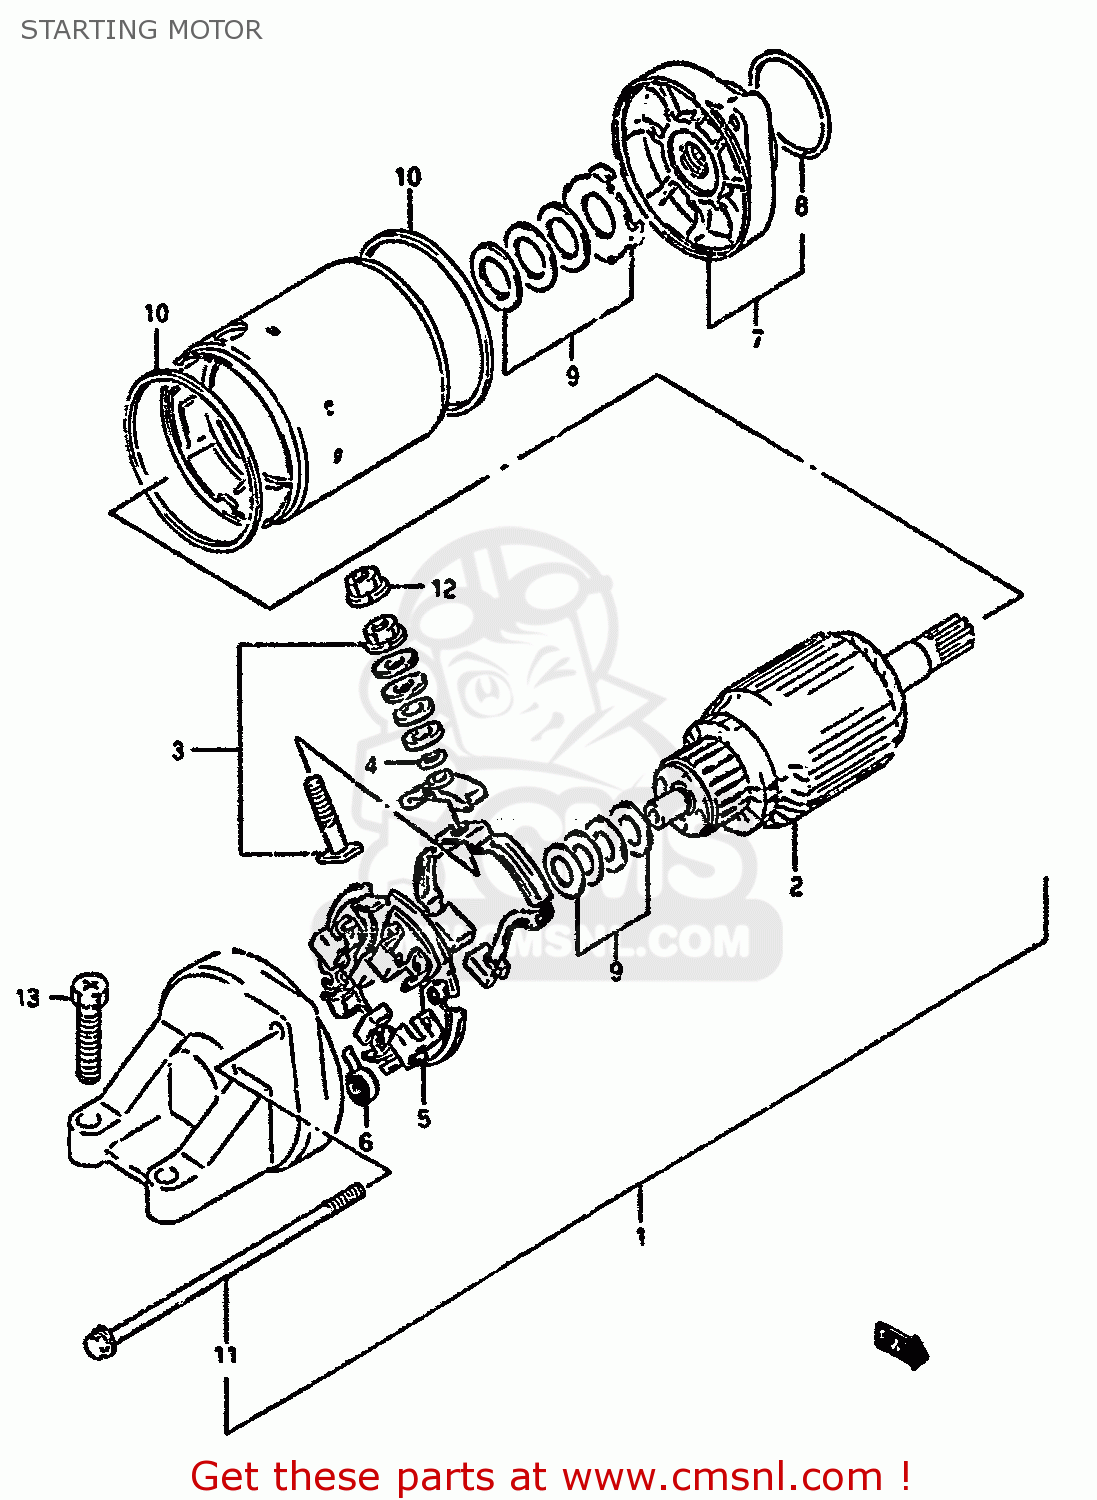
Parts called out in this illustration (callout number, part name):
1	MOTOR ASSEMBLY,STARTING (SI
2	ARMATURE
3	TERMINAL SET,BRUSH
4	O RING
5	HOLDER SET,BRUSH
6	SPRING,BRUSH
7	BRACKET ASSY,FR
8	O-RING
9	SHIM SET,STARTING MOTOR
10	O RING
11	BOLT
12	NUT
13	SCREW (6X25)
